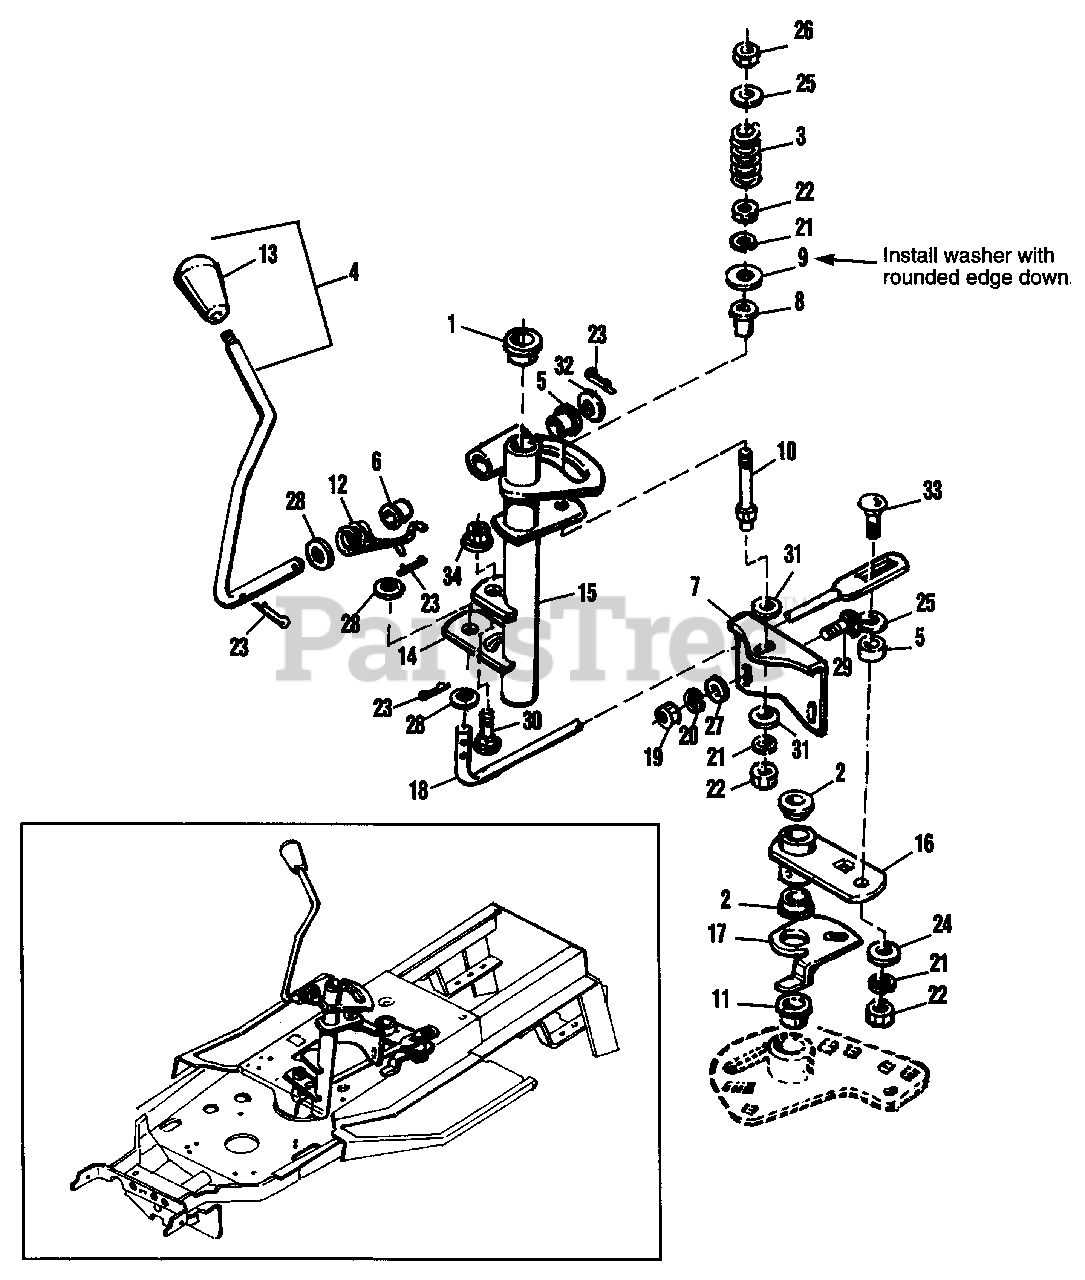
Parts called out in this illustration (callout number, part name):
1	BUSHING, Plastic, 3/4
2	BUSHING, Plastic
4	LEVER, Shift (Incl. Ref. No. 13)
6	BUSHING, Plastic, 1/2
7	BRACKET, Tension
9	WASHER, Special
11	BUSHING, Plastic
12	SPRING, Torsion
13	KNOB, Shift Lever
14	LEVER, Shift Adjuster
15	SHIFT LEVER ASSY.
16	PIVOT ASSY., Shift
17	LEVER, Lockout
18	SHIFT ROD, Front
19	NUT, Hex, Full, 1/4-20
20	LOCKWASHER, 1/4
21	LOCKWASHER, 5/16
22	NUT, Hex, Full, 5/16-18
23	COTTER PIN
24	WASHER, Plain, 5/16
25	WASHER
26	NUT, Hex, Nylon Lock, 5/16-18
27	WASHER, Plain, 1/4
28	WASHER
29	CARRIAGE BOLT, 1/4-20 x 3/4
30	CARRIAGE BOLT, 3/8-16 x 1
33	CARRIAGE BOLT, 5/16-18 x 1-1/4
34	NUT, Hex, Flange Lock, 3/8-16
